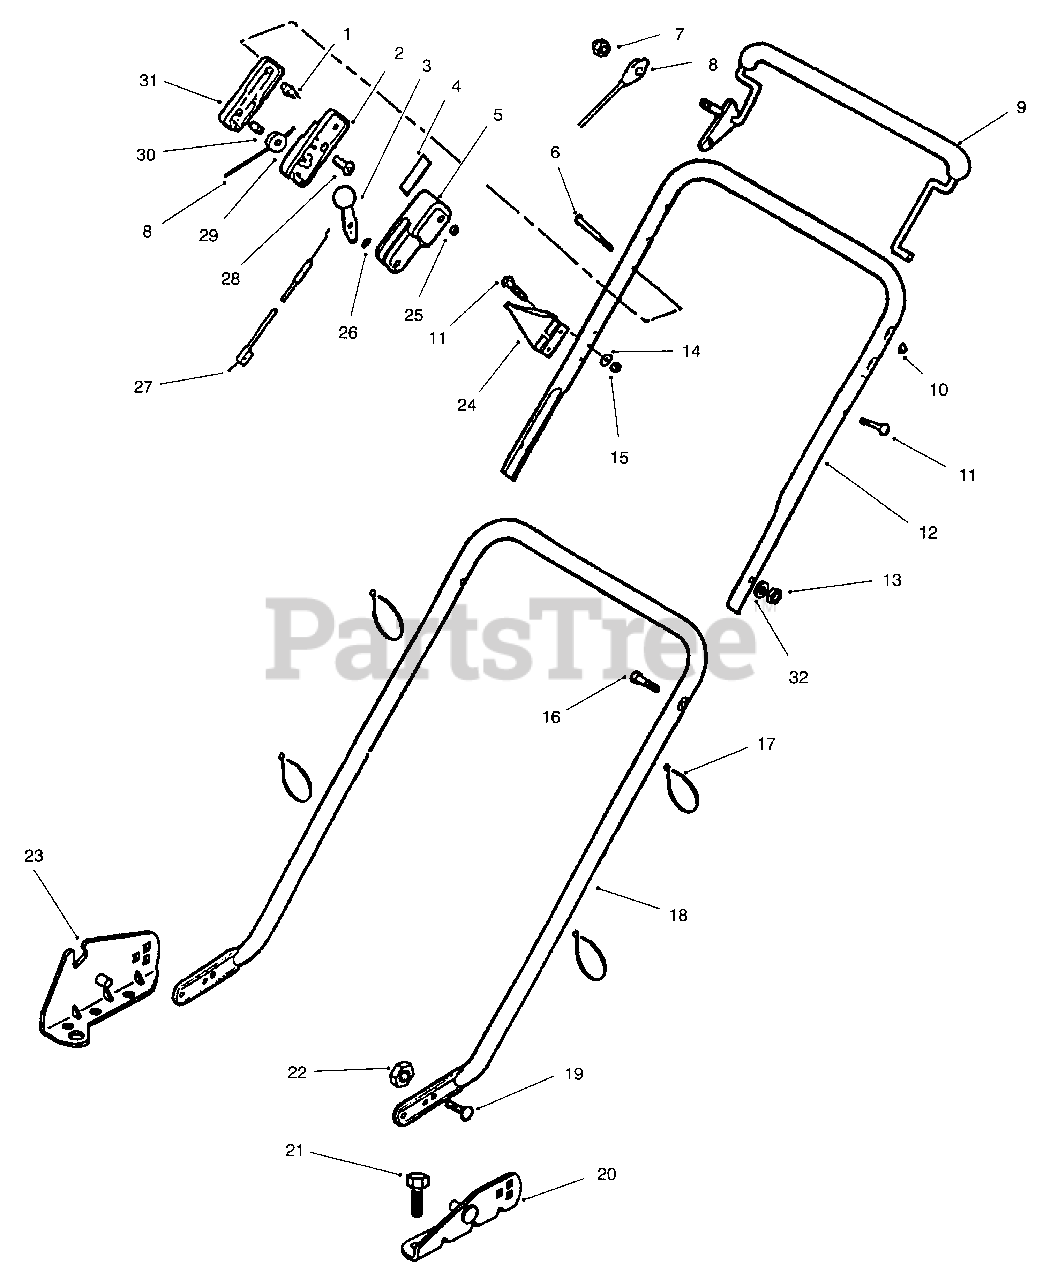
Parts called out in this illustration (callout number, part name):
2	Case-Throttle, Center
3	Assembly-Knob & Lever
4	Decal-Control, Throttle
5	Case-Throttle, Inner
7	Nut-Acorn
8	Cable-Control
9	Assembly-Lever, Control
10	Palnut
12	Handle-Top
13	Nut-Handle
17	Strap-Tie
18	Handle-Lower
19	Bolt
20	Bracket-Handle, L.H.
23	Bracket-Handle, R.H.
24	Assembly-Guide, Rope
27	Cable-Throttle
30	Pin-Pulley
31	Case-Throttle, Outer
32	Washer-Screw, Handle
